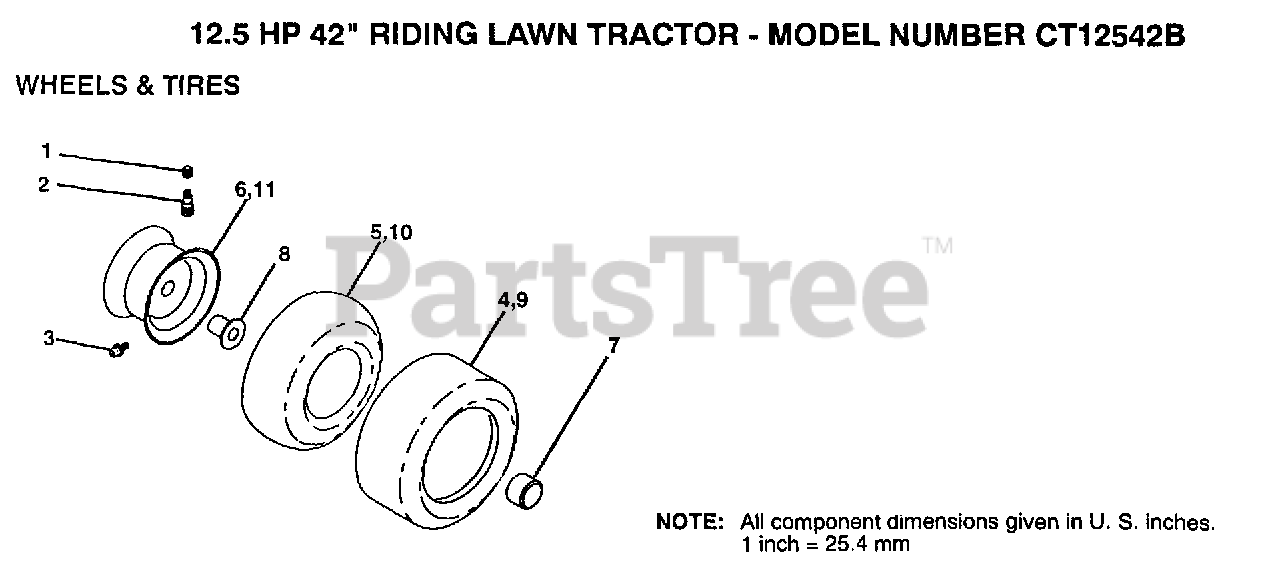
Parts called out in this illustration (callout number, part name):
1	VALVE CAP
2	VALVE STEM LT
3	FITTING LT
5	TUBE.5.3/4.5/6
7	HUB CAP
8	"FLANGE, BEARING"
10	TUBE.18X9.5-8
